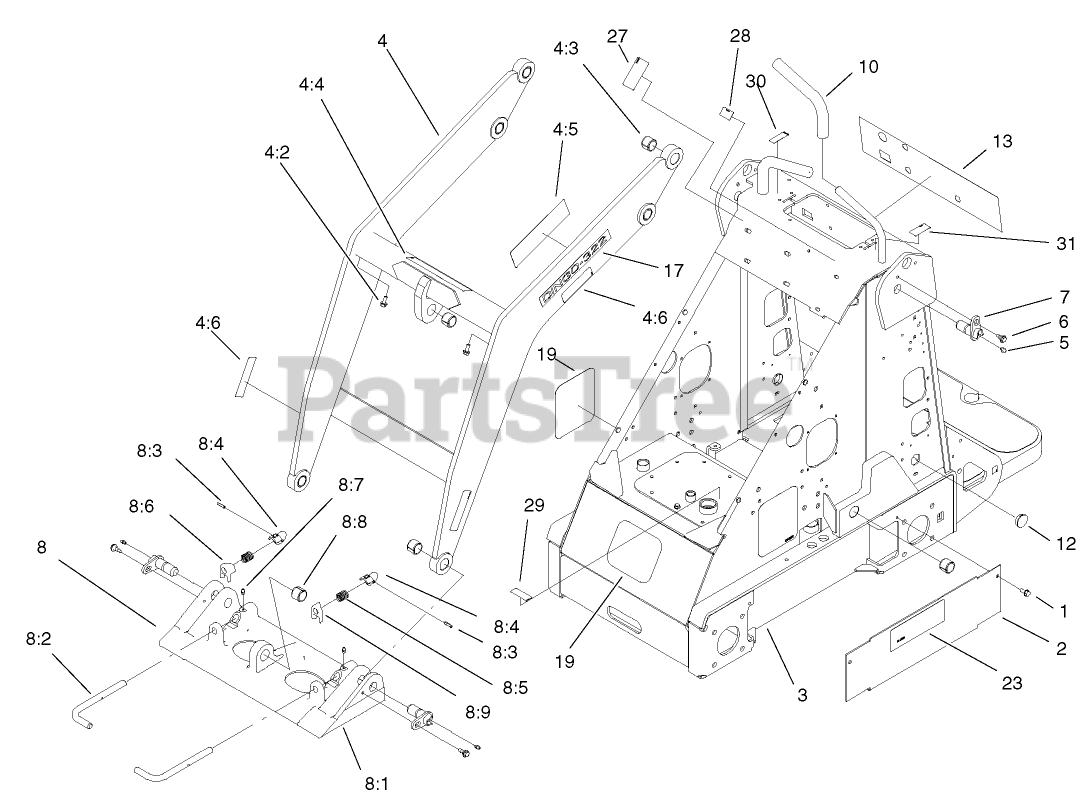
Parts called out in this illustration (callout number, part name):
1	SCREW-HWHTF
2	COVER-HOSE
3	FRAME ASM
4	LOADER ASM
4:2	SCREW-HWHTF
4:3	BUSHING-TENSION
4:4	DECAL-CAUTION
4:5	DECAL-DANGER
4:6	DECAL-PINCH
5	FITTING-GREASE
6	BOLT-SHOULDER
7	PIN-PIVOT
8	QUICK ATTACH ASM
8:1	MOUNT-ATTACH, QUICK
8:2	PIN-LOCKING
8:3	PIN-GROOVED
8:5	SPRING-COMPRESSION
8:6	STOP-RH
8:7	FITTING-GREASE
8:8	BUSHING-TENSION
8:9	STOP-LH
10	GRIP-CUSHION
12	PLUG-HOLE
13	DECAL-PANEL, CONTROL
17	DECAL - DINGO 322
19	DECAL
23	DECAL-4-PAW
27	DECAL-POWER, AUXILIARY
28	DECAL-LIMITER, SPEED
29	DECAL-OIL, HYD
30	DECAL-CHOKE
31	DECAL-THROTTLE
